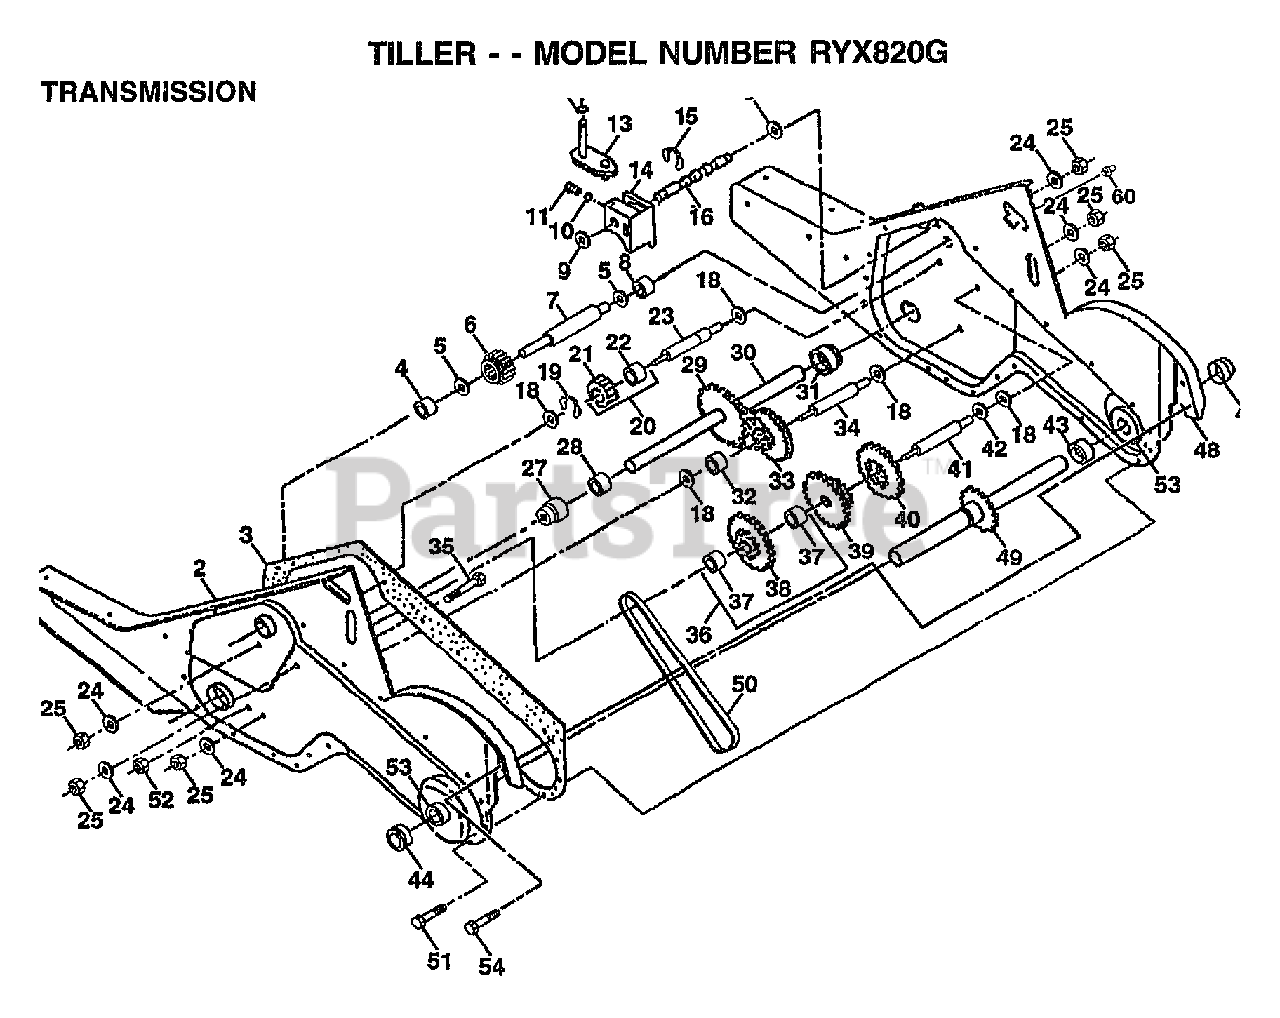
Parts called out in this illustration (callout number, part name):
1	TRANSMISSION ASSY
2	GEARCASE LH W/BEARING
3	GASKET.GEARCASE
4	NEEDLE BRNG LT
5	"T, BEARING"
6	GEAR PINION INPUT
7	"SHAFT.INPUT.""D"""
8	"TI, BEARING"
9	WASHER SEAL
11	SPRING-SHIFT CRT
12	O-RING TI
13	BRACKET ASM SHIFT
14	SHIFT FORK TI
15	KLIP RING
16	SHAFT.SHIFTER
18	WASHER
19	KLIP RING
20	GEAR ASSY CRT
21	GEAR-REV IDLR CRT
22	NEEDLE BEARING TI
23	SHAFT CRT
24	LOCKWASHER
25	NUT.ASF.HEX.7/16
27	BEARING.SHAFT.LH.
28	BUSHING TI
29	CHAIN CRT
30	GROUND SHAFT ASSY
31	BEARING.SHAFT.RH.
32	SPACER TI
33	SPRCKT 8 GEAR CRT
34	SHFT 2ND RED. CRT
35	SCRW WHIZ LOK CRT
36	SPROCKET.ASM.W/BR
37	BEARING
39	GEAR TI
40	GEAR TI
41	REDUCTION SHFT TI
42	BRNG RACE
43	SPACER TI
44	SEAL ASM-OIL
48	GEARCASE W/BEARING
49	TINE SHAFT
50	CHAIN.50 LINK TI
51	SCREW
52	NUT.HEX.5/16-18
53	KIT.BEARING
54	SCREW
60	ZERK M
